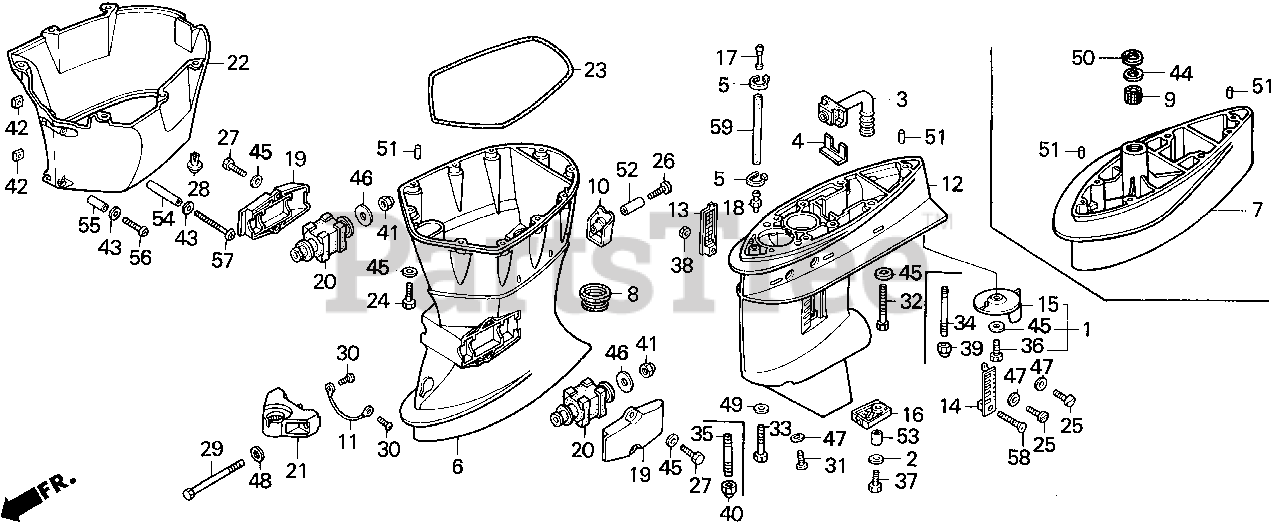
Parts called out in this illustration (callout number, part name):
1	TAB KIT, TRIM
2	WASHER, PIVOT
3	TUBE, WATER (LOWER)
4	PLATE, RUBBER SETTING
5	BAND, WIRE
6	CASE, EXTENSION *NH282MU* (L) (OYSTER SILVER METALLIC-U)
8	RUBBER, DRAIN PLUG
10	COVER, DRAIN PLUG *NH282MU* (OYSTER SILVER METALLIC-U)
11	WIRE, LEAD
12	CASE, GEAR *NH282MU* (OYSTER SILVER METALLIC-U)
13	SCREEN, R. WATER
14	SCREEN, L. WATER
16	SCREEN, WATER (LOWER)
17	END, NIPPLE
18	NIPPLE, SENSOR
19	HOUSING, R. MOUNTING (LOWER) *NH282MU* (OYSTER SILVER METALLIC-U)
20	RUBBER, SETTING (LOWER)
21	HOUSING, CENTER MOUNTING (LOWER) *NH282MU* (OYSTER SILVER METALLIC-U)
22	COVER (LOWER) *NH282MU* (OYSTER SILVER METALLIC-U)
23	RUBBER, COVER (LOWER)
24	BOLT, HEX. (8X35)
25	BOLT, OIL CHECK (8X8)
26	SCREW, SPECIAL (6X35)
27	BOLT, HEX. (8X25)
28	SCREW, RIVET (8X15)
29	BOLT, HEX. (12X162)
30	SCREW, PAN (6X8)
31	BOLT, DRAIN PLUG (8MM)
32	BOLT, HEX. (8X65)
33	BOLT, HEX. (10X40)
36	BOLT, HEX. (8X20)
37	BOLT, HEX. (6X16)
38	NUT, SELF-LOCK (5MM)
41	NUT, SELF-LOCK (12MM)
42	NUT, PLATE (5MM)
43	WASHER, PLAIN (5MM)
45	WASHER, PLAIN (8MM)
46	WASHER, PLAIN (12MM)
47	WASHER, NYLON (8MM)
48	WASHER, PLAIN (12MM)
49	WASHER, PLAIN (10MM)
51	PIN, DOWEL (6X10)
52	COLLAR, DISTANCE (6X10.5X25)
53	COLLAR, WATER SCREEN (LOWER)
54	COLLAR, DISTANCE (5X7X38)
55	COLLAR, DISTANCE (5X7X23)
56	SCREW, PAN (5X30)
57	SCREW, PAN (5X45)
58	SCREW, OVAL (5X32)
59	BULK HOSE, VACUUM (5X3000) (5X200)
